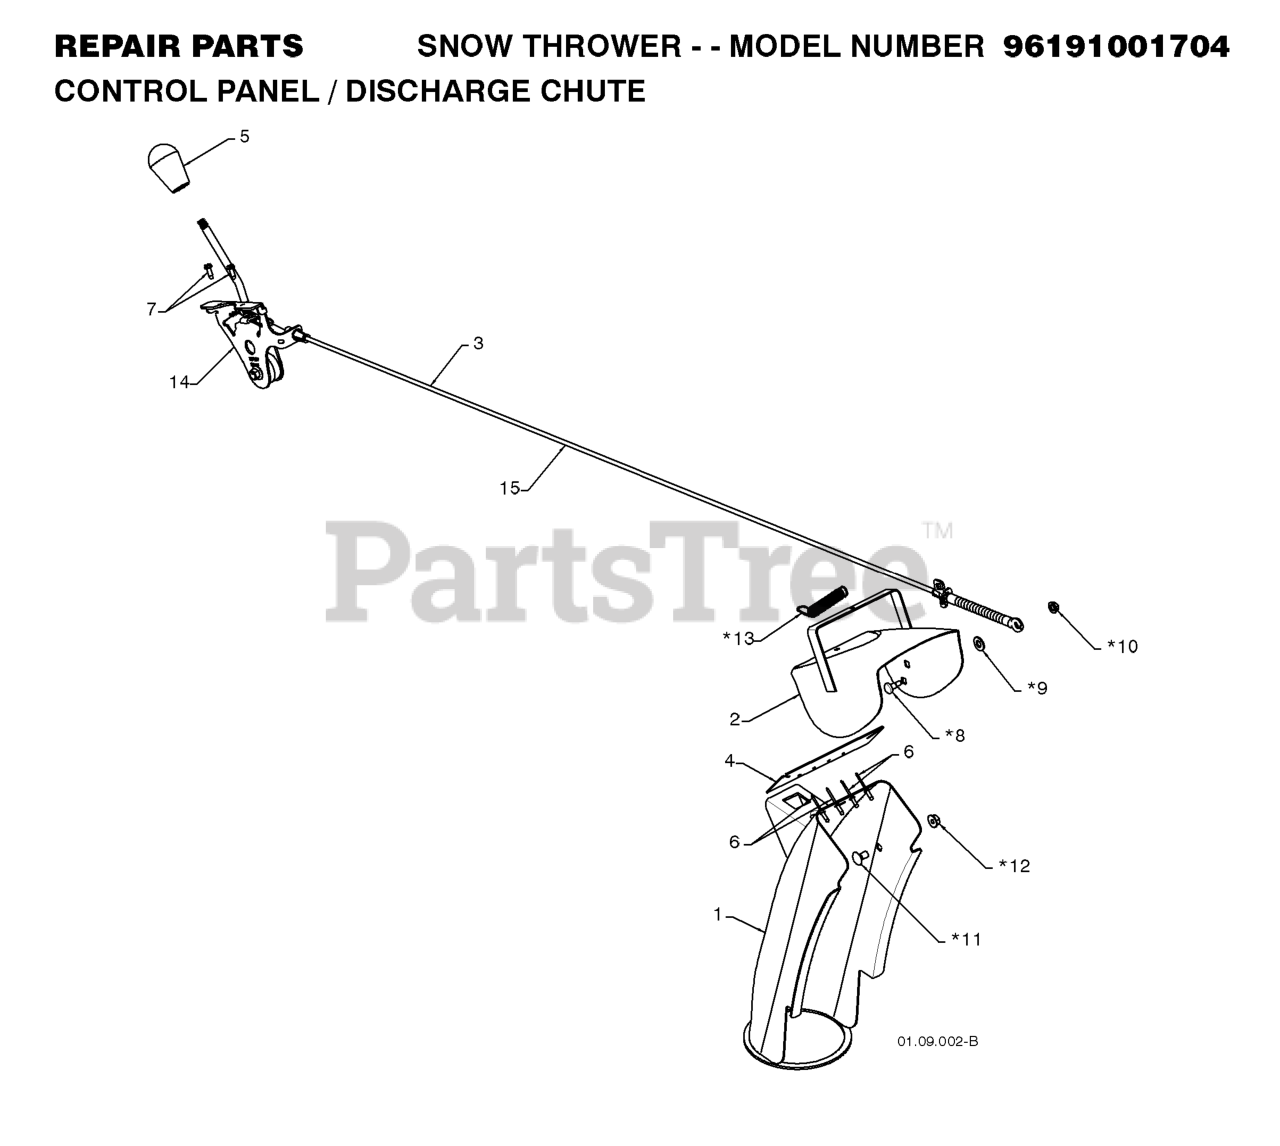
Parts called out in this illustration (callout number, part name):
1	CHUTE ASSEMBLY
2	DEFLECTOR.WELDMENT.PNT.ORANGE
3	RP.CONTROL.ASM.DEFLECTOR.SNOW
4	SEAL.DEFLECTOR
5	KNOB LEVER, BLACK
6	RIVET BLIND
7	SCREW #10-24 X 5/8
14	RP CNTRL.HEAD.ASSEM.DEFLECTOR
15	RB SERVICE.CHUTE.DEF.CBL.BLK
